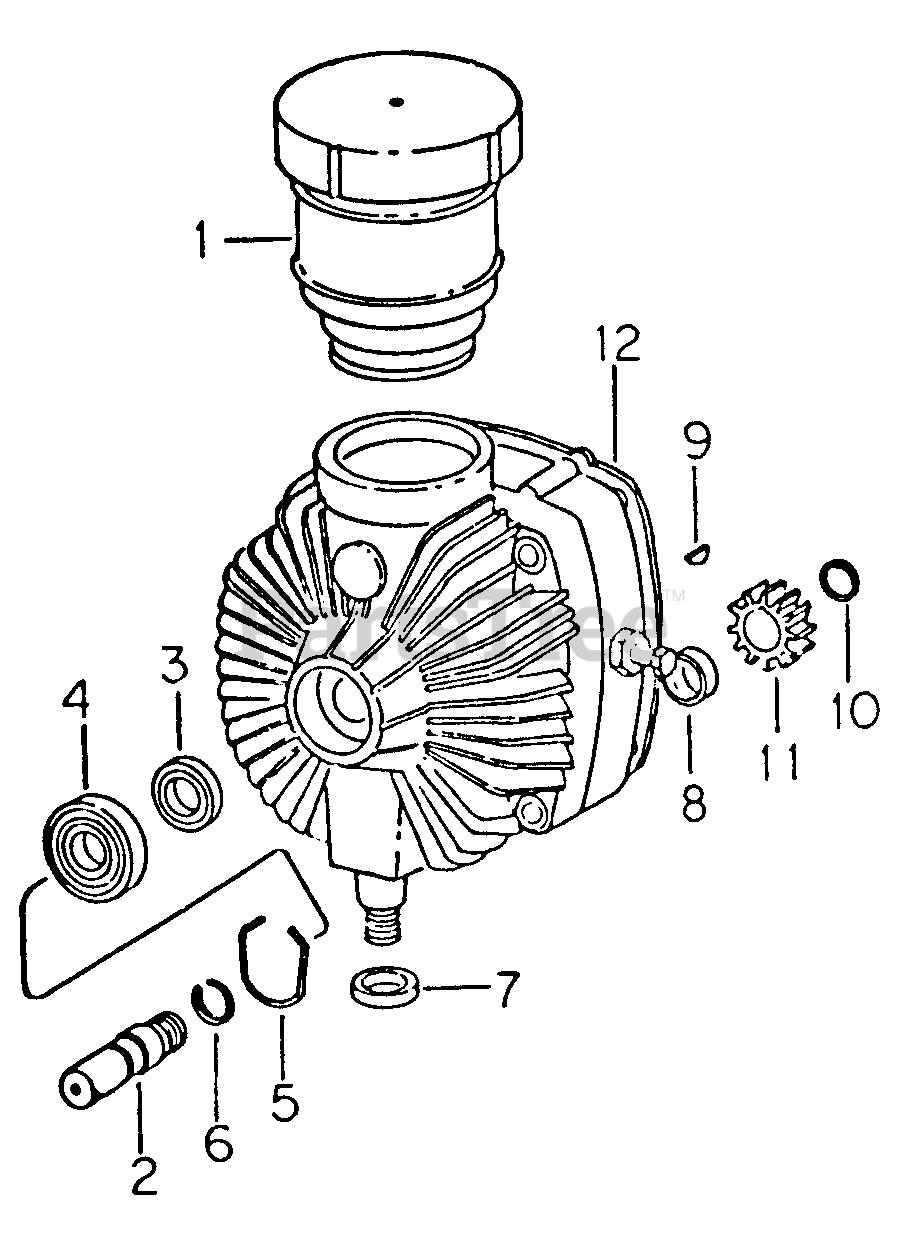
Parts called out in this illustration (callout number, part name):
1	Kit, Reservoir Service
3	Seal, Oil
4	Bearing Assy, Ball
7	Seal, Oil
9	Key, 1/8 X 1/2 Woodruff 3
10	Ring, Retaining
12	Gasket, Hydrostatic Drive
